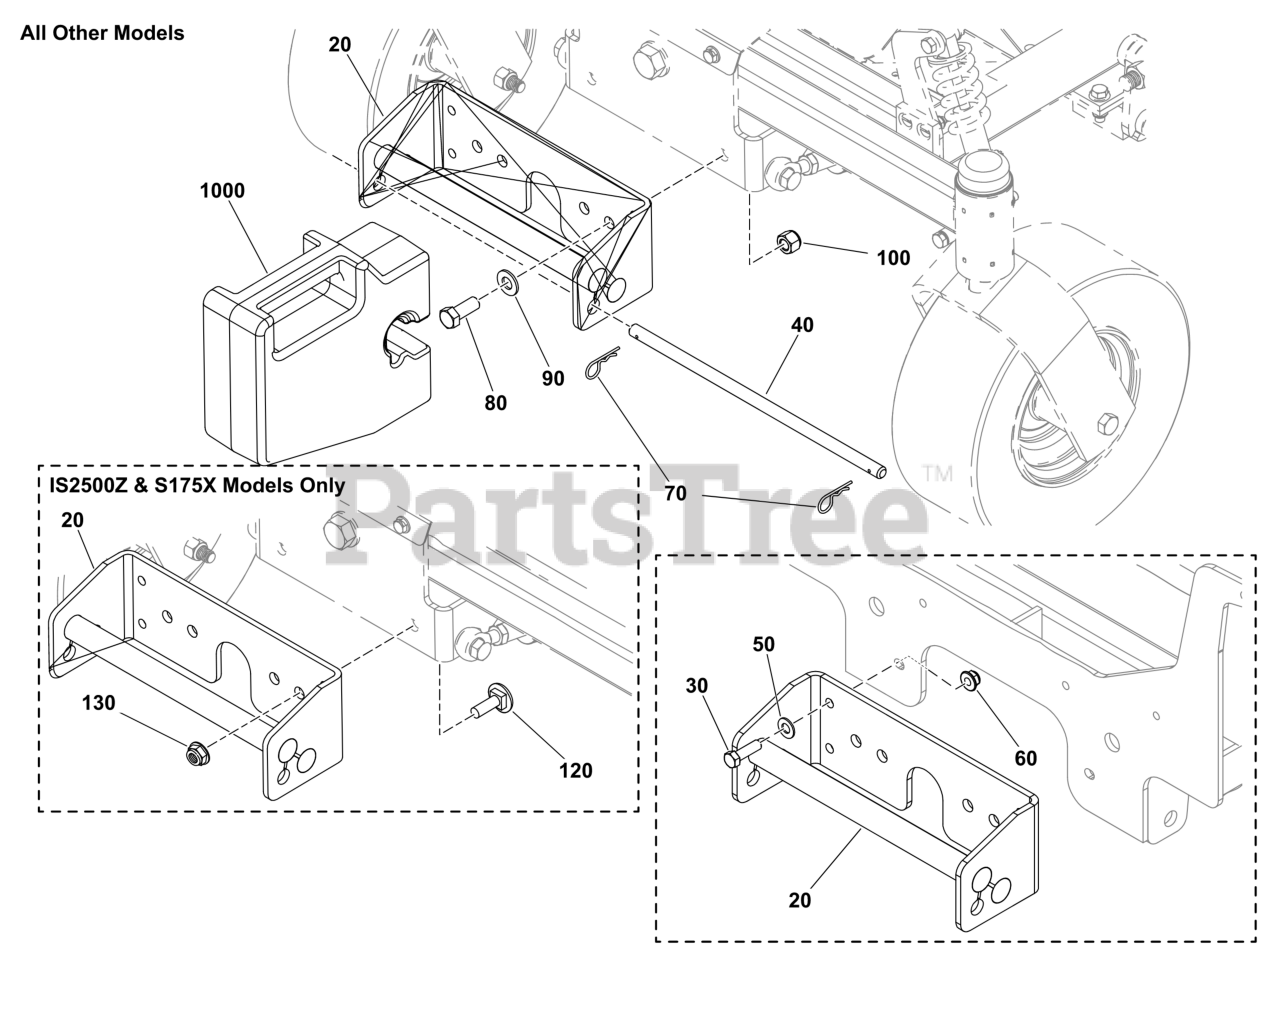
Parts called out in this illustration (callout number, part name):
20	HOLDER ASSEMBLY, Weight
30	BOLT, 3/8-16 X 1-1/4"
40	ROD-.500DIA 13.75LG Y
60	NUT, 3/8-16 HEX NYLOCK
70	PIN, HAIR, .0915 X 1-7/8
80	BOLT, 1/2-20 X 1-1/4"
90	WASHER, 1/2" SAE
100	NUT, 1/2-20 HEX NYLON
1000	WEIGHT - 33LBS
